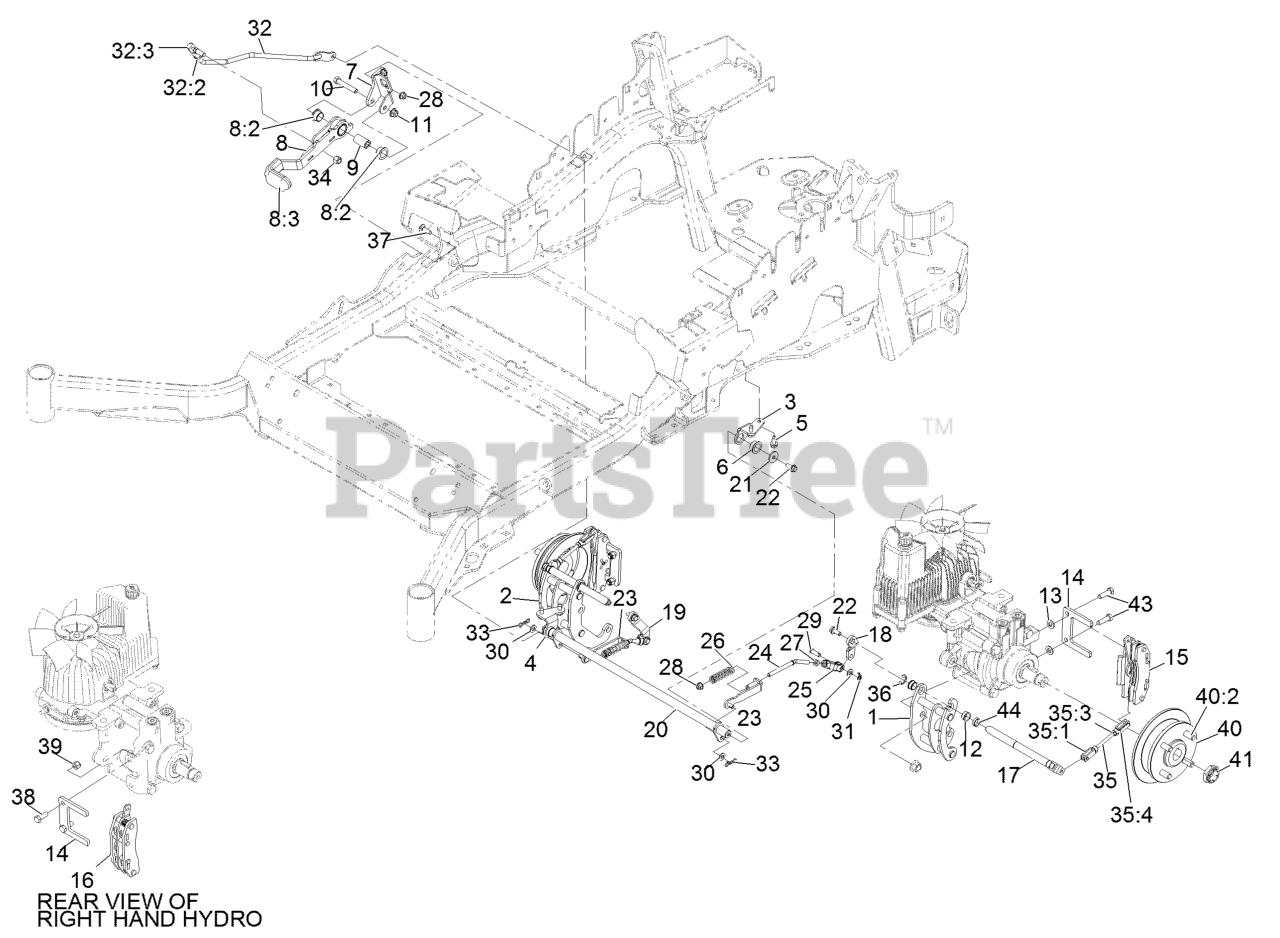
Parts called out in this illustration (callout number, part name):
1	MOUNT-BELLCRANK, LH
2	MOUNT-BELLCRANK, RH
3	MOUNT-PIVOT, LH
4	MOUNT-PIVOT, RH
5	Screw-HWH 5/16-18 X 3/4 Tf
6	BUSHING-FLANGE
7	BRACKET-MOUNT
8	BRAKE LEVER ASM
8:2	BUSHING-FLANGE
8:3	GRIP-LEVER
9	HANDLE-PIVOT, BRAKE
10	SCREW-HH
11	NUT-HF, NI
12	BUSHING
13	WASHER-FLAT
14	PLATE-MOUNT, BRAKE
15	CALIPER-BRAKE
16	CALIPER-BRAKE, RH
17	BELLCRANK
18	ARM-INNER, LH
19	ARM-INNER, RH
20	SHAFT-CROSS
21	WASHER-FLAT
22	SCREW-HHF
23	BRACKET-L
24	LINKAGE-MID
25	YOKE-OFFSET
26	SPRING-COMPRESSION
27	NUT-JAM
28	NUT-HF, NI
29	PIN-CLEVIS
30	WASHER-PLAIN
31	PIN-COTTER, LOCKING
32	FRONT LINKAGE ASM
32:2	END-TIE ROD, RH
32:3	NUT-HJ
33	PIN-COTTER, LOCKING
34	NUT-LOCK
35	REAR LINKAGE ASM
35:3	NUT-JAM
35:4	PIN-CLEVIS, SPRING
37	BOLT-CARR
38	SCREW-HH
39	NUT-LOCK, NI
40	WHEEL HUB ASM
40:2	STUD-WHEEL
41	LOCKNUT
43	SCREW-LOCK, PATCH
